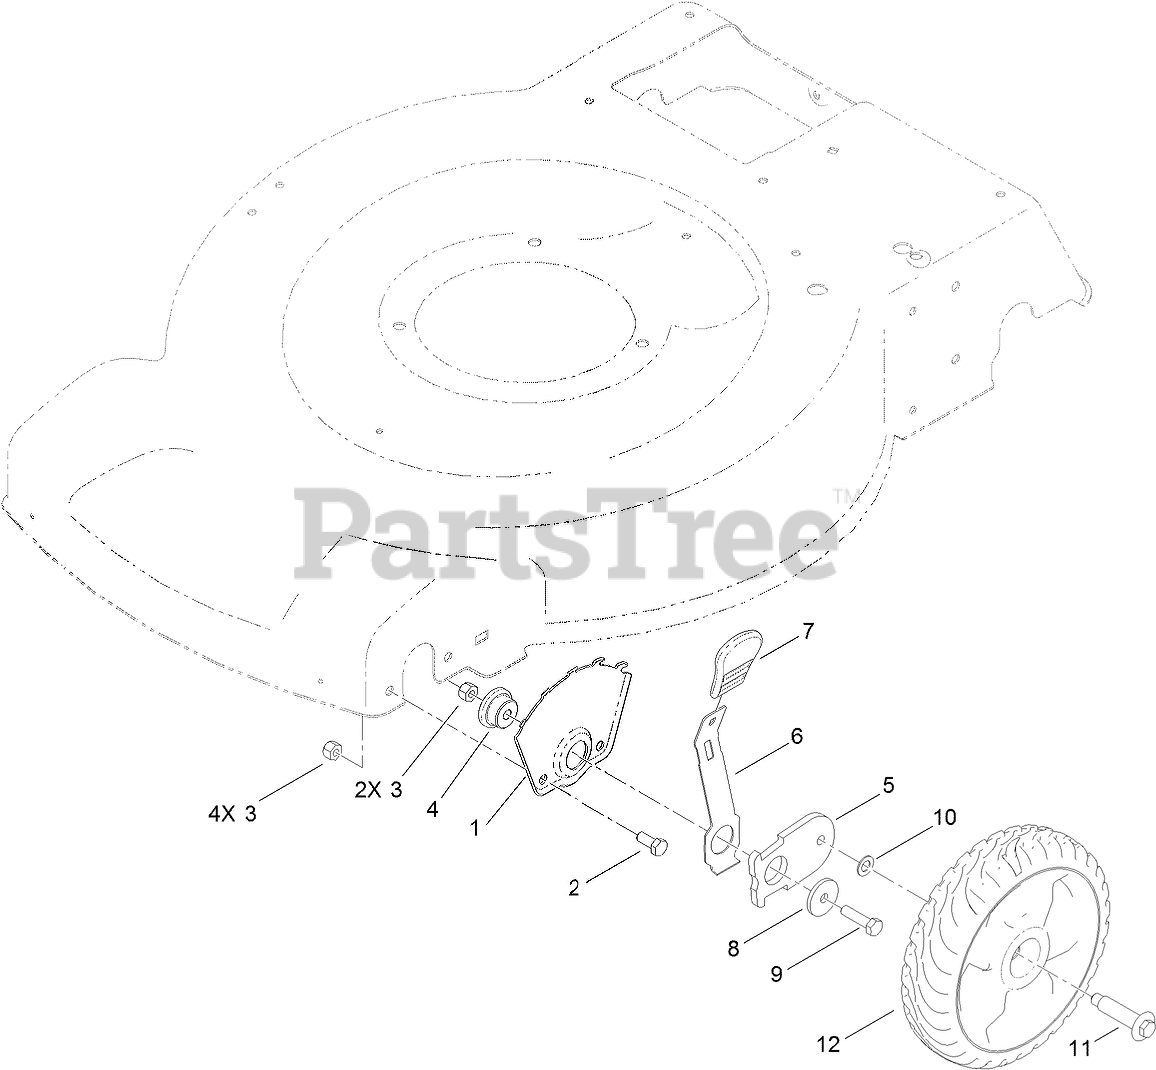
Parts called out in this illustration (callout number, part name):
1	PLATE-HOC, FRONT
2	SCREW-HH
3	NUT-LOCK, NI
4	Bushing-Mount, HOC
5	ARM-PIVOT, FRONT
6	Arm-Spring
7	KNOB-HOC
8	Washer-Flat
9	SCREW-HH
10	WASHER
11	BOLT-SHOULDER
12	8 INCH WHEEL ASM
